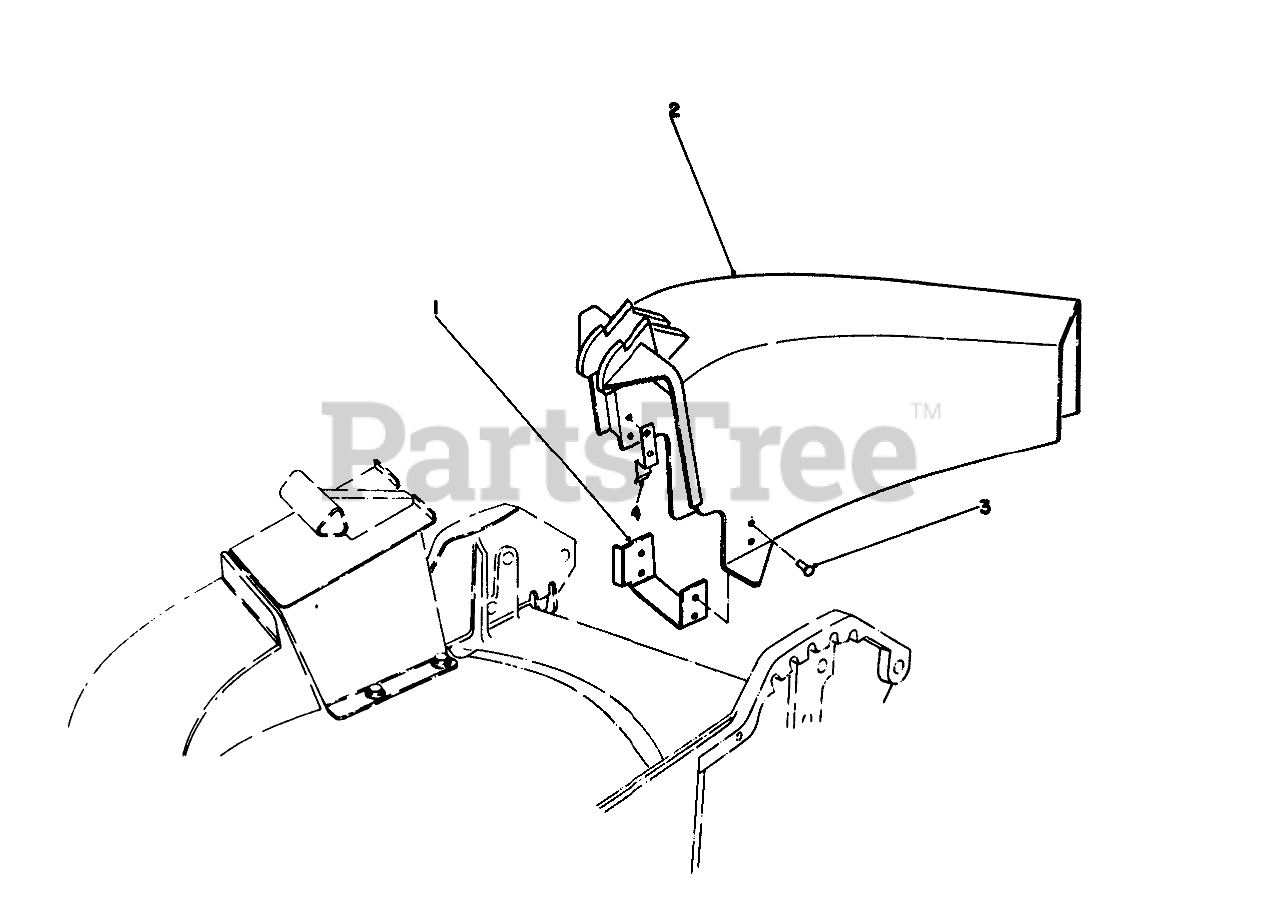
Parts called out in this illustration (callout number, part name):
1	CHUTE BRACKET
2	Discharge Chute Assembly (Incl. Ref. #1, 3, & 4)
3	RIVET
4	CHUTE TAB
